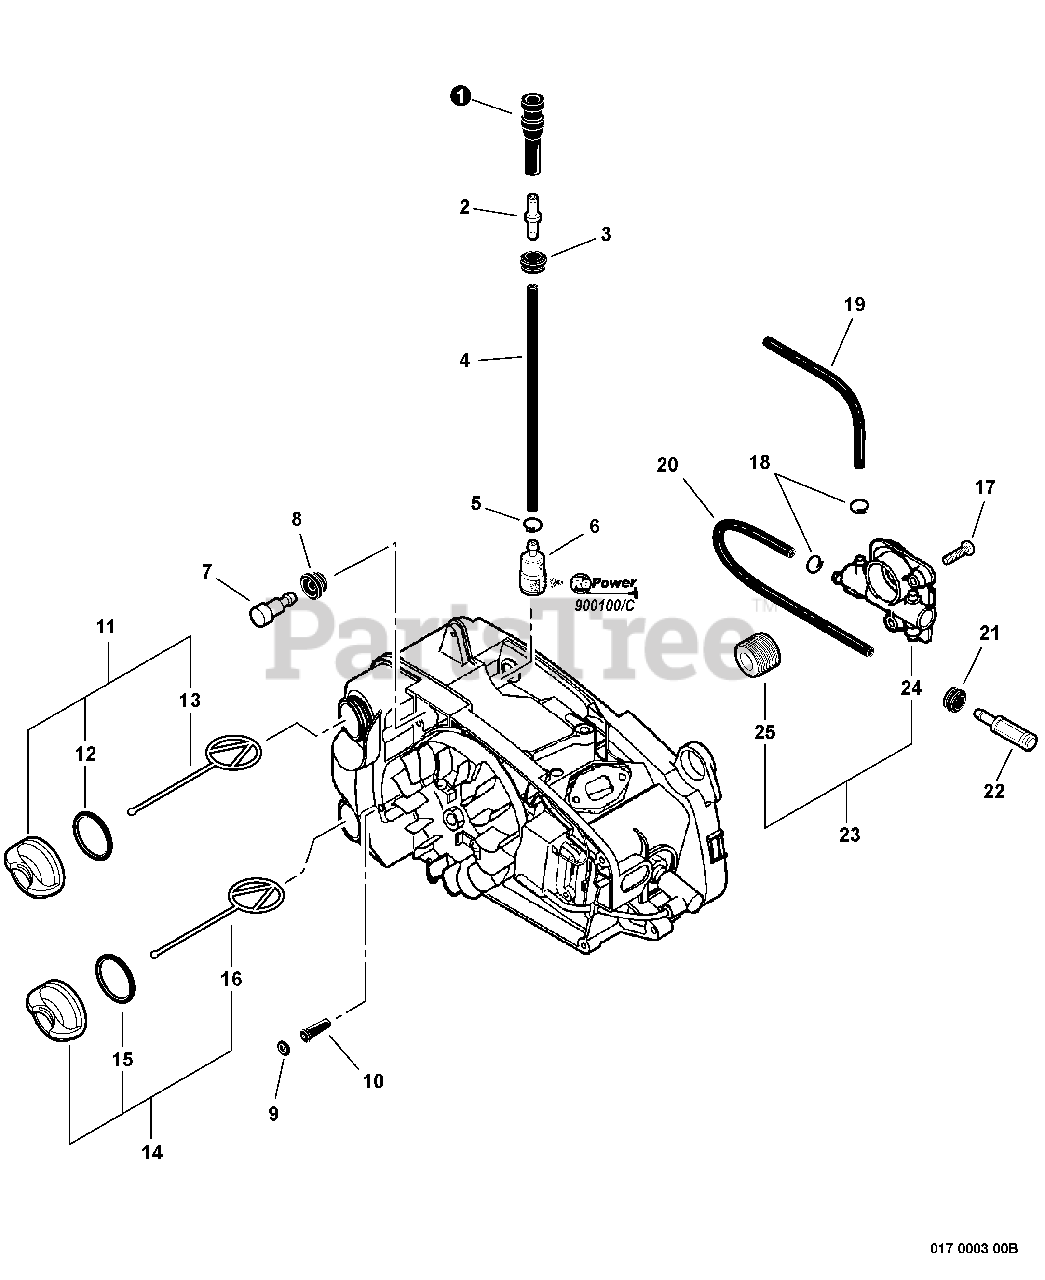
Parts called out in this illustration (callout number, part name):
1	PIPE - FUEL
2	CONNECTOR, PIPE
3	GROMMET
4	PIPE
5	CLIP - 6
6	FILTER, FUEL
7	VENT, FUEL TANK
8	GROMMET
9	O-RING - 4
10	VENT, TANK
11	CAP ASSY - ORANGE
12	O-RING - 18
13	CONNECTOR, CAP
14	CAP ASSY - BLACK
15	O-RING - 18
16	CONNECTOR, CAP
17	SCREW - 4X12
18	CLIP - 6.5
19	PIPE - 3X6X90 -- BLACK
20	PIPE - 3X5X195 -- BLACK
21	GROMMET
22	FILTER, OIL
23	AUTO-OILER ASSY
24	AUTO-OILER ASSY
25	GEAR - WORM
26	RePower TUNE-UP KIT
